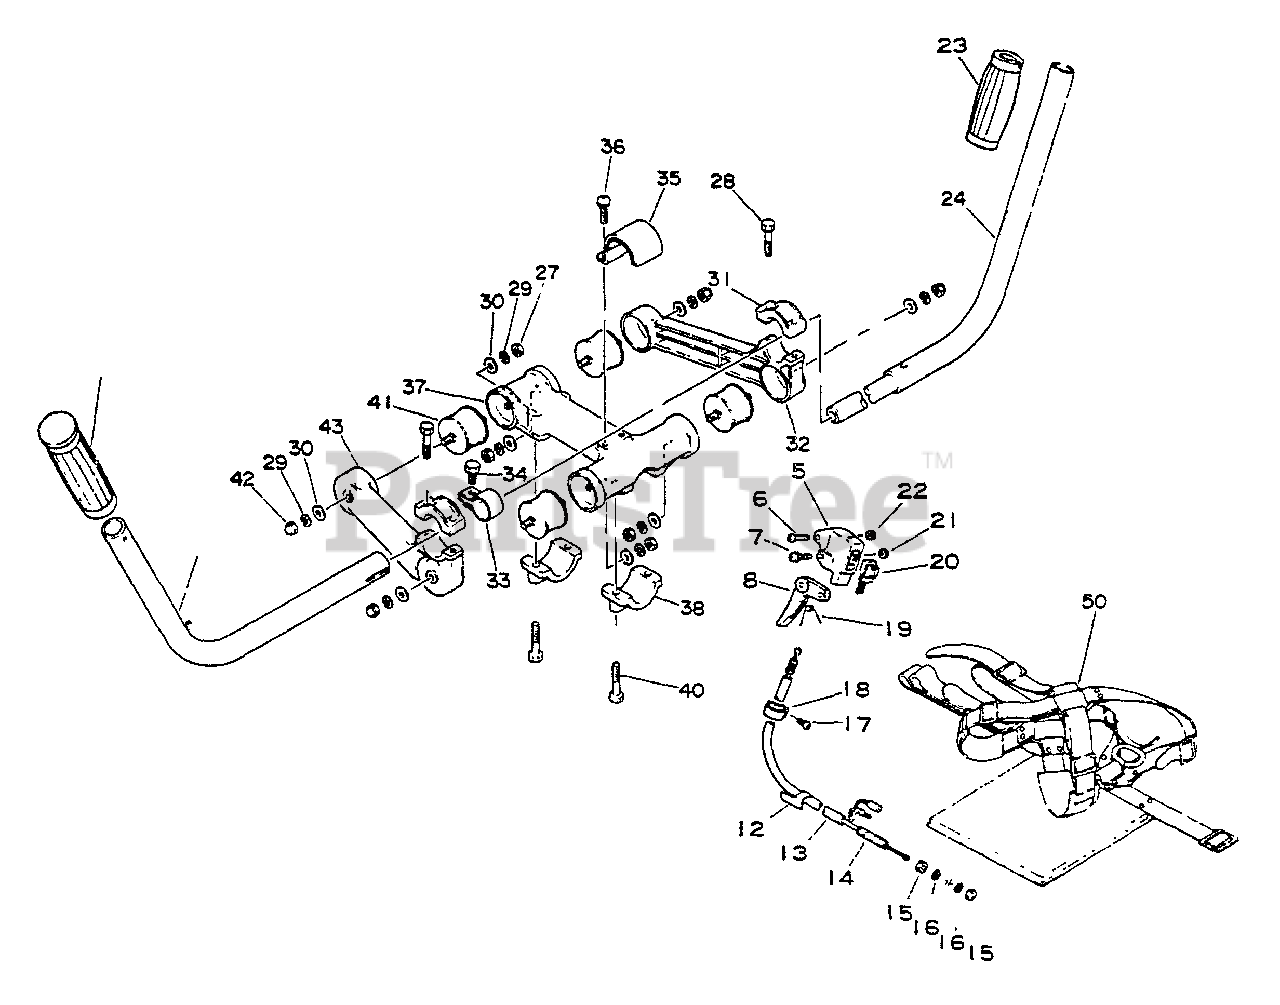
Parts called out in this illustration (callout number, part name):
5	BRACKET, THROTTLE
6	SCREW - 5X30
7	SCREW - 5X30
8	TRIGGER, THROTTLE
13	TUBE - VINYL
14	CABLE, THROTTLE
15	LOCKNUT - 6
16	WASHER - 6
17	SCREW - 5X10
19	SPRING, TRIGGER
20	IGNITION SWITCH ASSY
22	LOCKNUT - 5
23	GRIP, HANDLE
28	BOLT - 5X25
29	LOCKWASHER - 5
30	WASHER - 5
31	RETAINER
32	ARM, RETAINER - RIGHT
33	CLAMP
34	SCREW - 6X12
35	PLATE
36	SCREW - 5X14
37	Holder, d.s. housing
38	HOLDER
40	BOLT - 6X30
41	CUSHION
42	NUT - 5 -- CAP
43	ARM, HANDLE - LEFT
44	HANDLE
45	GRIP, HANDLE - LEFT
50	SHOULDER STRAP ASSY
